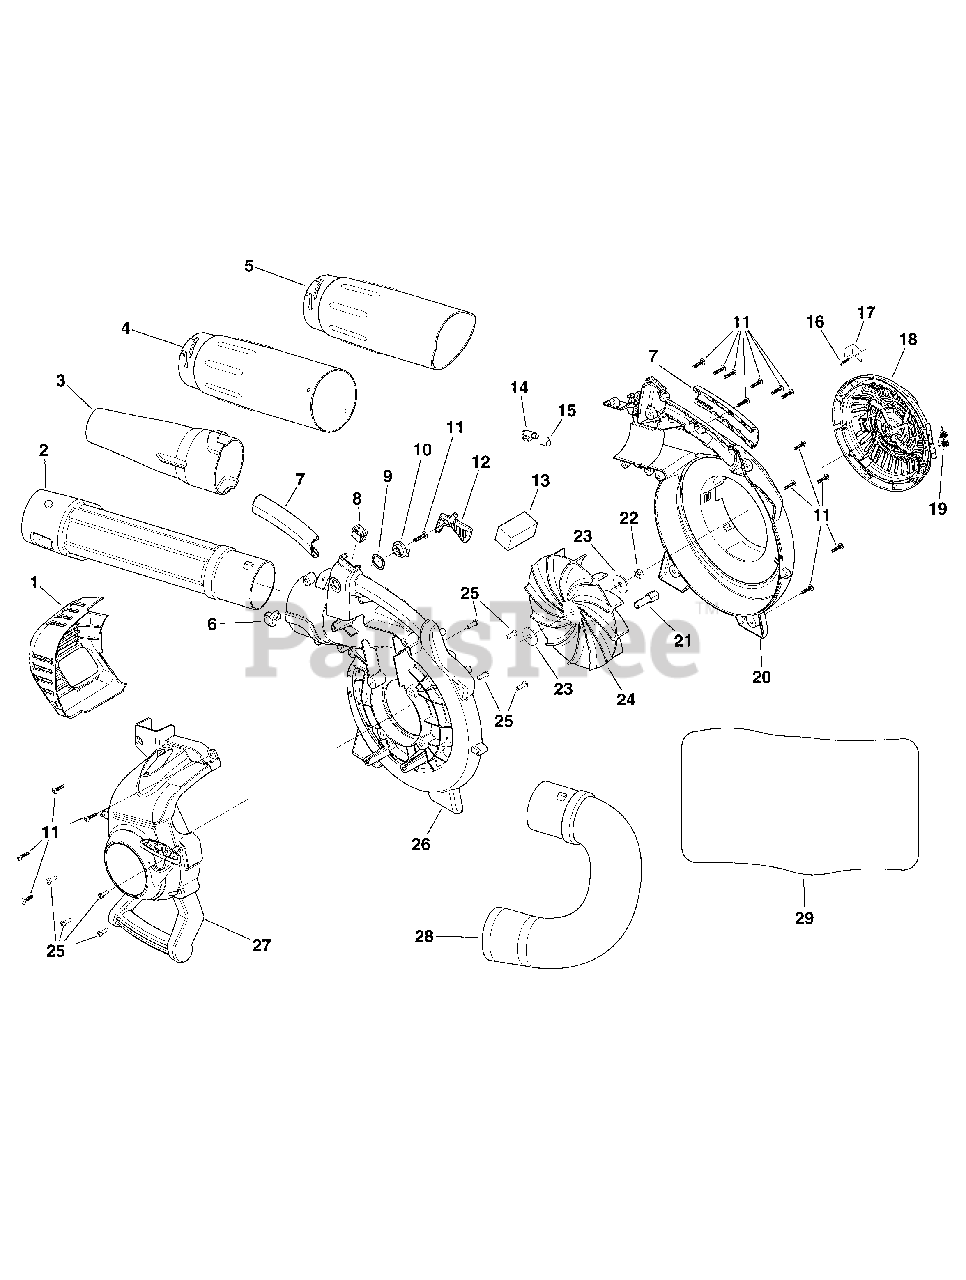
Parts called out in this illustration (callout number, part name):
1	ASSEMBLY, Muffler Cover
2	TUBE, Upper
4	TUBE, Upper Vac
5	TUBE, Lower Vac
6	TRIGGER LOCK, Outer
7	GRIPS, Handle
8	ASSEMBLY, Ttigger Switch
9	WASHER, Wavy
10	TRIGGER LOCK, Inner
12	TRIGGER, Throttle
13	FILTER, Foam
14	TUBE, Latch
15	SPRING, Latch
17	LOCK, Door
18	COVER, Intake
20	HOUSING, Impeller, Front
21	ADAPTER
24	IMPELLER
25	SCREW, Starter
26	HOUSING, Impeller, Rear
27	ASSEMBLY, Engine Cover
